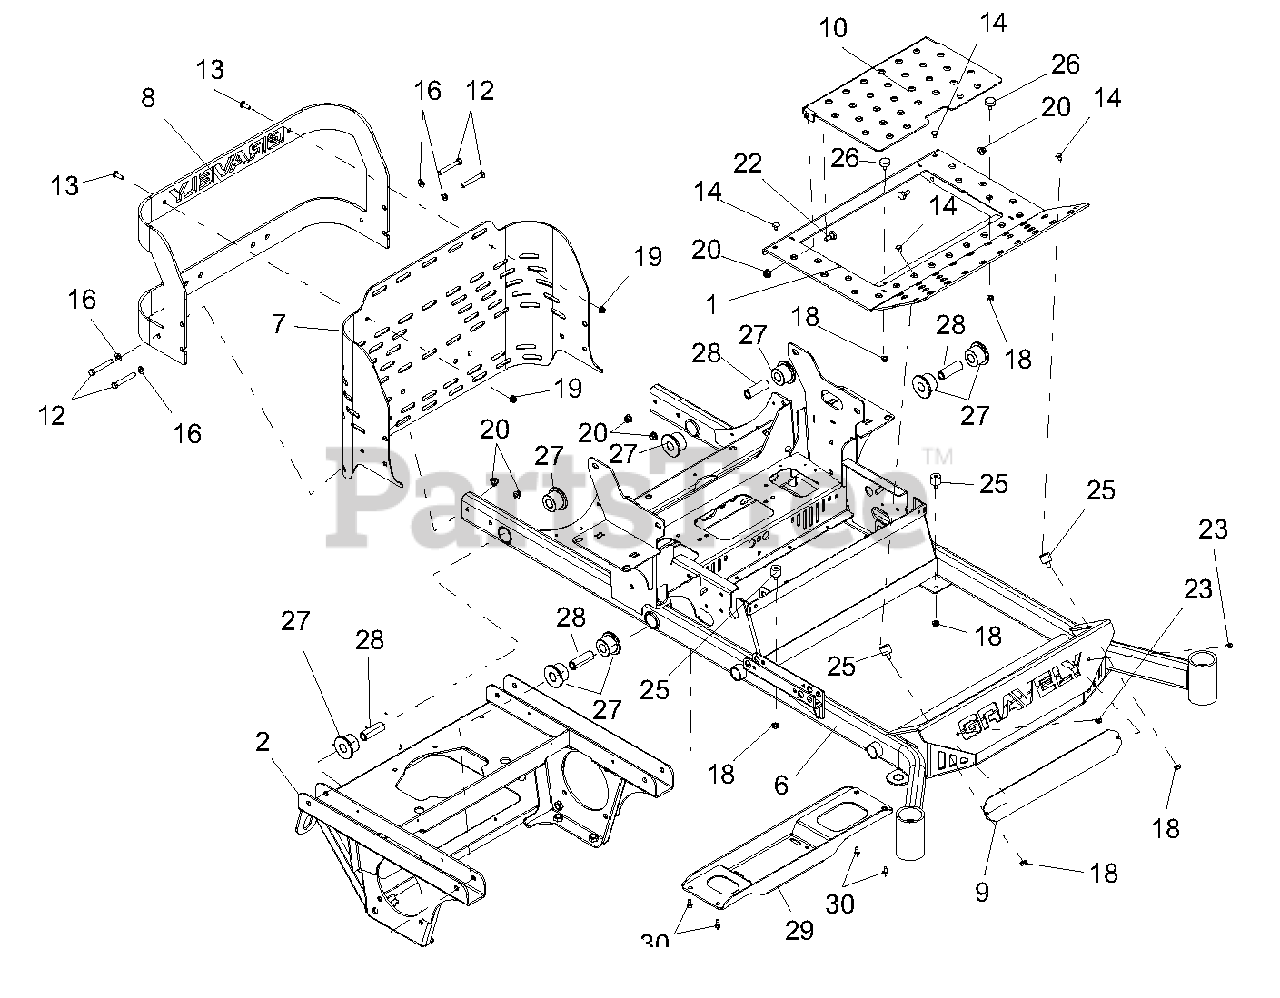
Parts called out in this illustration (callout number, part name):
1	WLDMT, FOOT PLATE
2	WLDMT, 200PT AXLE/ENGINE FRAME
3	HOSE, HYD .38-11-OK M6N0-M6N0
6	WLDMT, PT400 MAIN FRAME (992207, 230, 231, 232, 233, 234, 235)
7	GUARD, REAR BUMPER FINGER
8	BUMPER, PT400 REAR
9	PLATE, BUMPER LOGO BACKING
10	PANEL, INSPECTION
12	BLT-HEX .38-16X2.75 GR5 YWZC
13	BLT-RDHDSQSHNK .31-18X1.00 G5YWZC
14	BLT-RDHDSQNK .31-18X.50 G5 YWZC
16	WSHR-FL-STL.406X.812X.065 YWZ
18	NUT-SPNLK-FLG .312-18 YWZC
19	NUT-LK-NYL-FLG .31-18 YWZC
20	NUT-LK-NYL-FLG .38-16 YWZC
22	BLT, SHLDR EP .38-16X.30 HEX YZ
23	SCR-TAP .25-20X.50 HWH TR YWZ
25	BUMPER, STUD MOUNTED W/FEMALE INSERT
26	BUMPER, RUBBER
27	BUSHING, FLANGE .75X1.51X1.13X2.0 URE
28	BUSHING, SHEAVE .50X.75X2.23
29	PT400 GAS BATTERY TRAY
30	SCR-TAP .38-16X.75 HWH
